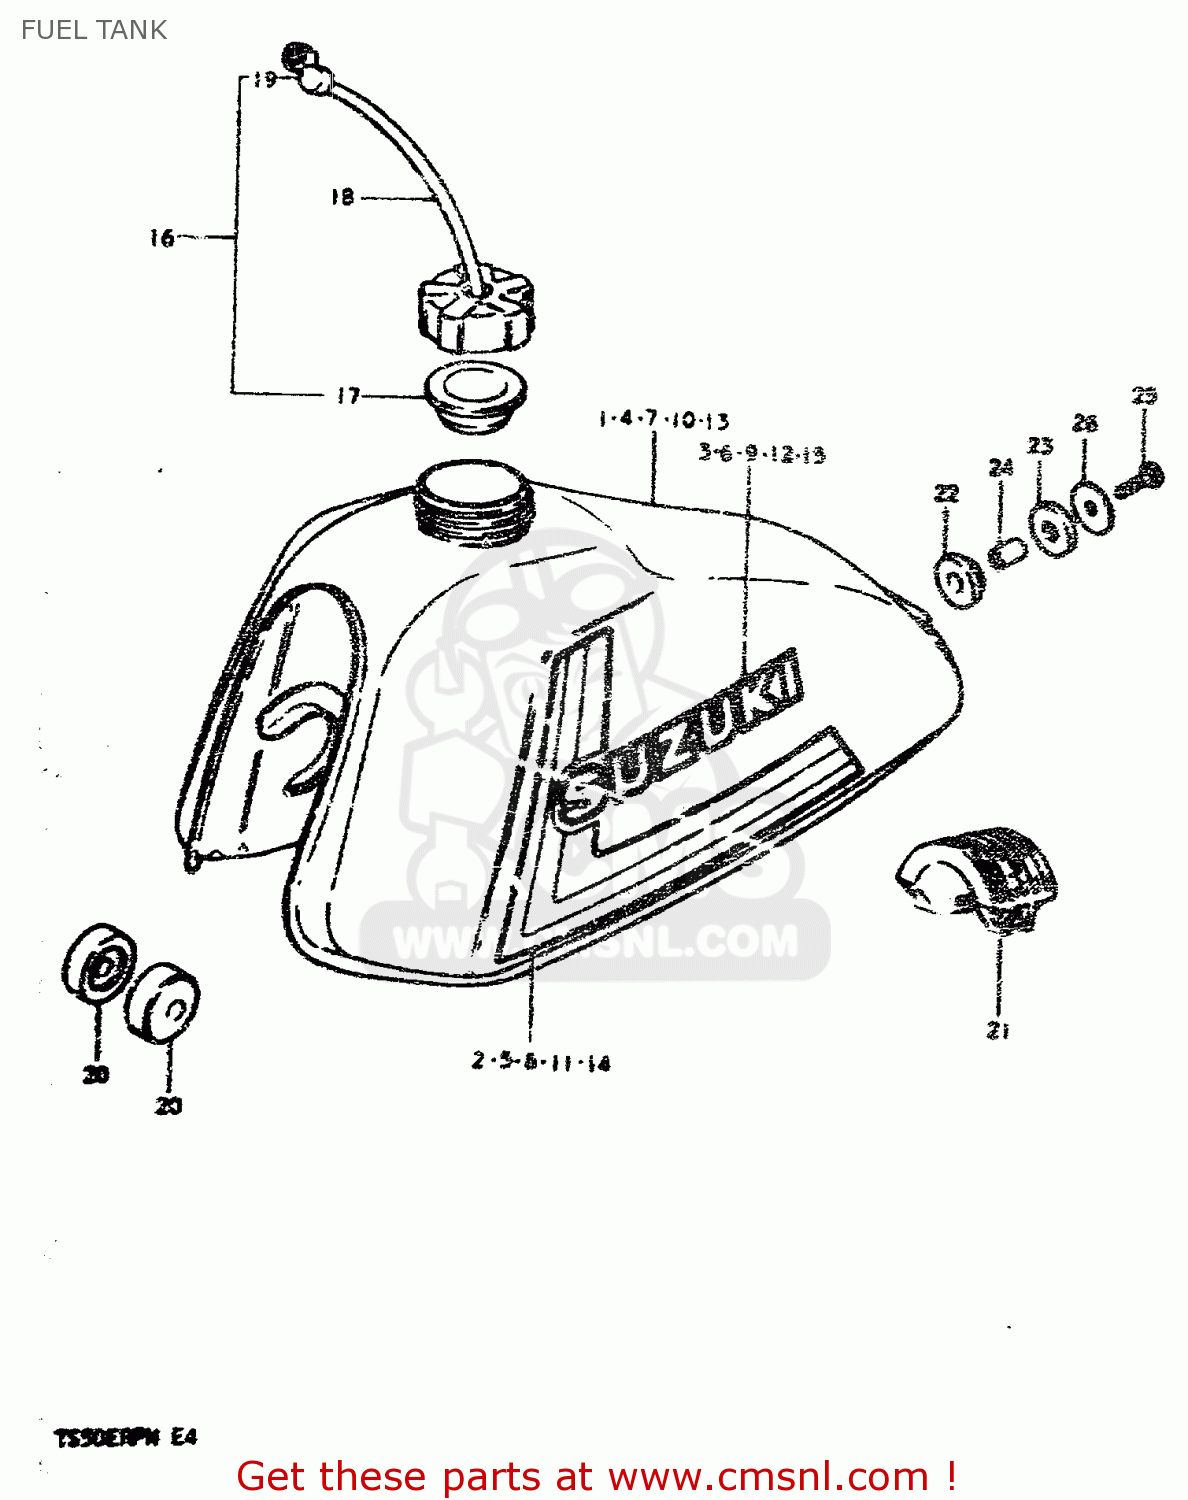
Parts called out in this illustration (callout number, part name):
1	TANK, FUEL (RED)
2	TAPE SET
3	EMBLEM
4	TANK, FUEL (BLUE)
5	TAPE SET
6	EMBLEM
7	TANK, FUEL (WHITE)
8	TAPE SET
9	EMBLEM(BLACK)
10	TANK, FUEL
11	TAPE SET
12	EMBLEM(BLACK)
13	TANK, FUEL (BLUE)
14	TAPE SET
15	EMBLEM
16	CAP SET,FUEL TANK
17	GASKET,FUEL TANK CAP (NAS)
18	HOSE
19	CLAMP,FUEL TANK BREATHER HOSE
20	CUSHION
21	CUSHION,FUEL TANK
22	CUSHION
23	CUSHION
24	SPACER(8.5X12X19)
25	BOLT (8X30)
26	WASHER (8.5X29X1.6)
